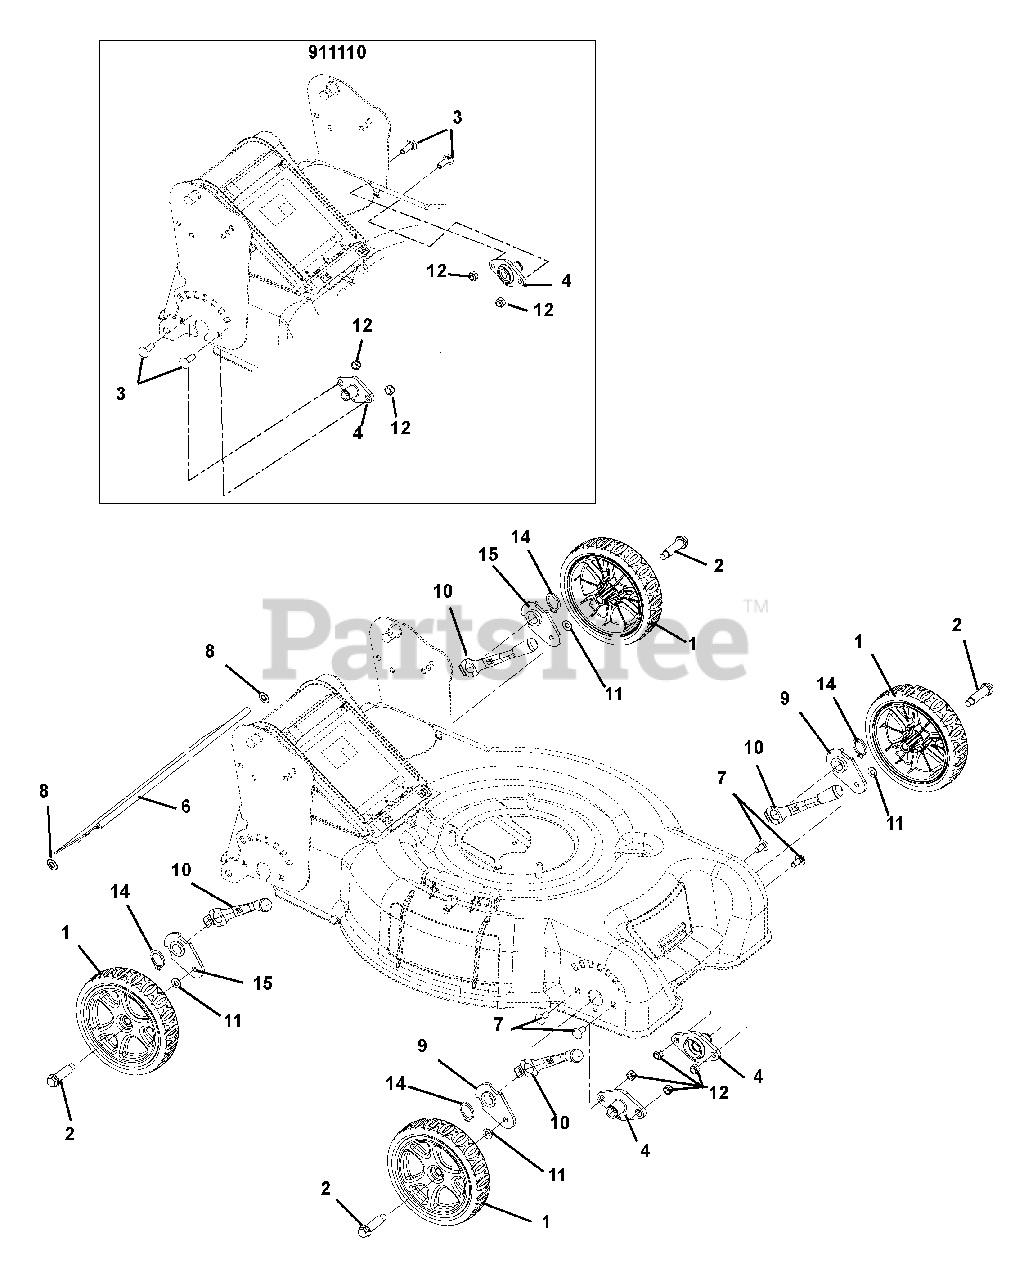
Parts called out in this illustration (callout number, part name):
1	WHEEL, 8.5" WBLM
2	BOLT, WHEEL SHOULDER
3	@BLT-RDHDSQNK .31-18X1.00 G5YZ
4	WHEEL MOUNT HUB
5	WHEEL MOUNT HUB
6	GUARD, WBLM
7	@BLT-RHDSSQNK .31-18X.75 G5YZ
8	RETAINER, .38 PUSH-ON
9	WELDM'T, FRONT WHEEL BRACKET
10	HANDLE, HOC
11	@WSHR-FL-STL.406X.812X.065 YWZ
12	@NUT-LK-TOP-FLG .31-18 YWZC
13	@NUT-LK-TOP-FLG .31-18 YWZC
14	RG-RTNG-EXT .689X.078
15	WELDM'T, REAR WHEEL BRACKET
